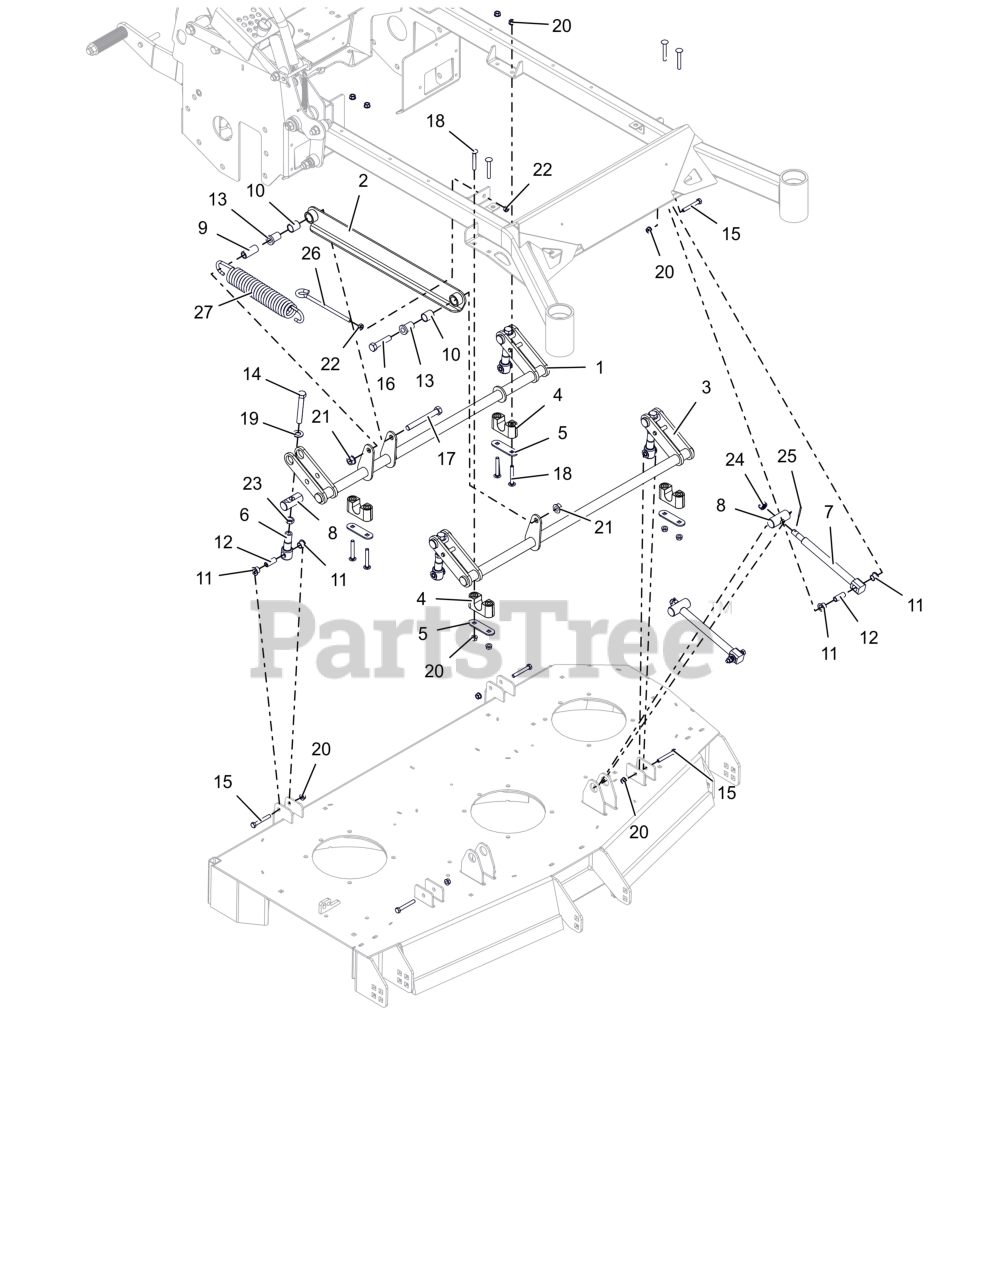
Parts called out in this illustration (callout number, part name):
1	WLDMT, DECK LIFT
2	LINK, DECK LIFT
3	WLDMT, FRONT DECK LIFT (BLACK)
4	ASM-BUSHING, DECK LIFT
5	PLATE, BEARING SUPPORT
6	LINK, DECK LIFT FORMED
7	DRAG,LINK-HD
8	PIN, DECK LIFT
9	BSHG, FLANGE .515 X .750 X 1.544 X 1.000
10	BRG, .750 X .875 X 1.000
11	BSHG, FLANGED .50X.625X.50X.062
12	SPCR, .31X.50X1.265
13	BSHG-FLG .515X.746X1.290X1.000
14	BLT, HEX 0.5-13X3.5F GR5 ZCC
15	BLT, HEX .31-18X2.25 G5 ZCC
16	BLT, HEX .50-13X2.25 G5 ZCC
17	BLT, HEX 0.5-13X4.25 GR5 ZCC
18	BLT, RHSSN.31-18X2.25 G5 ZCC
19	WSHR, FLT .557X1.040X.102 ZCC
20	NUT,LK-CTR-FLG .31-18 GF ZCC
21	NUT-LK-CTR-FLG .500-13 GG ZCC
22	NUT-JAM .375-16 G2 ZCC
23	NUT-JAM .500-13 G2 ZCC
24	NUT-SL .50-13
25	PIN,CTR.12X1.25EXTPRSQCT ZC120
26	BOLT, .38-16X6.00 .62 DIA EYE
27	SPRG, EXTENSION - .273X1.853X.10.125
